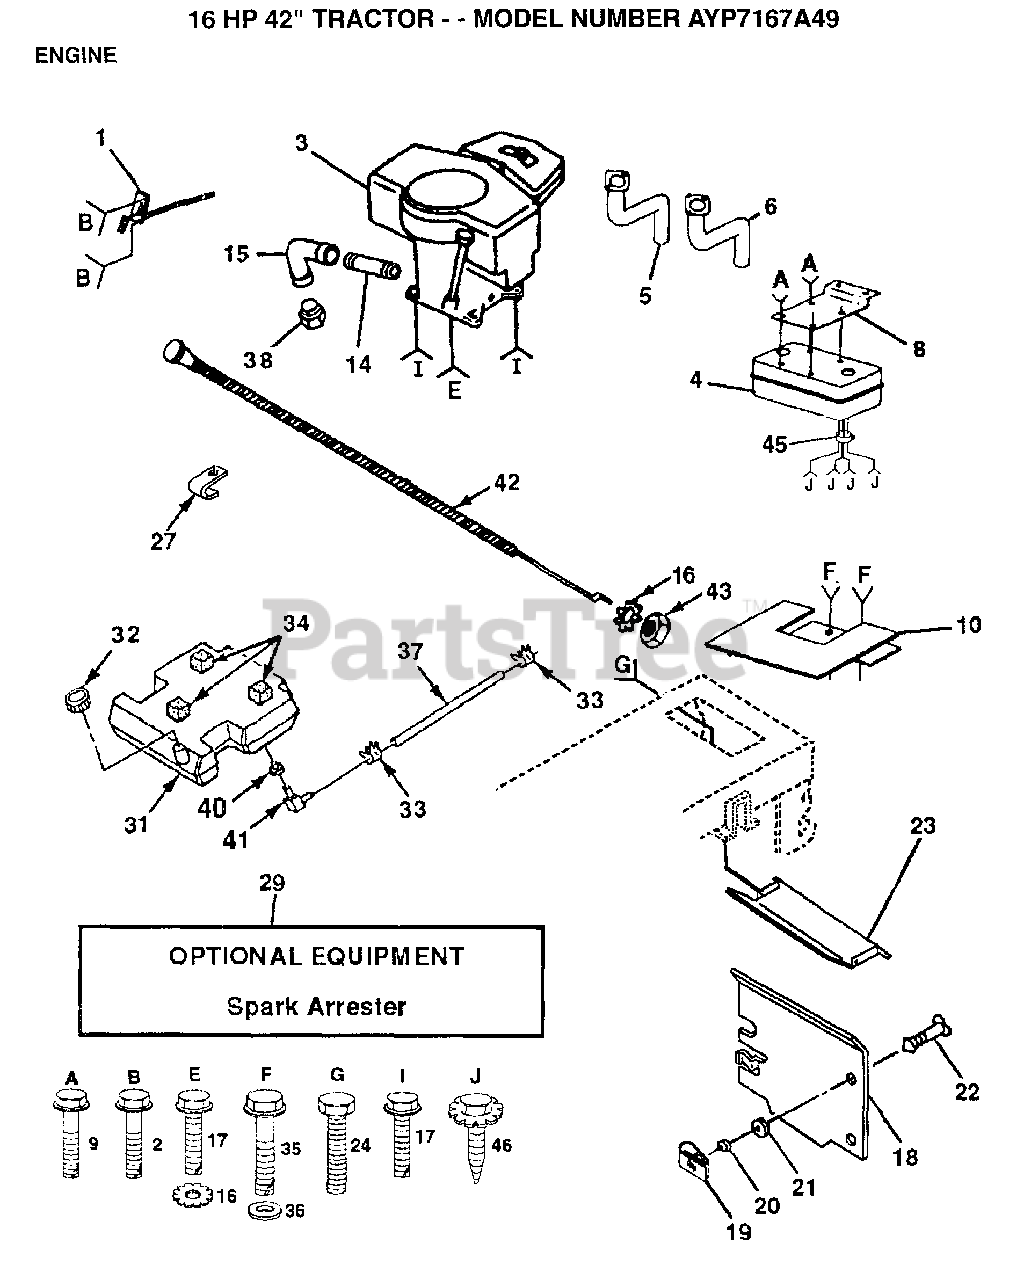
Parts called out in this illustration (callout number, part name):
1	CONTROL THRT 35.5
2	SCREW LT
5	TUBE ASSY EXH LH
6	TUBE ASSY EXH RH
8	BRACKET MUFFLER
9	SCREW ST
10	SHIELD HEAT LT
14	PIPE NIPPLE LT
15	ELBOW
16	LOCKWASHER
17	SCREW
18	SHIELD HEAT
19	RECEPTACLE LT
20	RETAINER LT
21	WASHER
22	STUD.1/4.TURN
23	HEAT SHIELD
24	SCREW
27	"CLIP,INSULATOR"
32	CAP ASM FUEL
33	HOSE CLAMP
34	PAD-SPACER LT
35	SCREW
36	WASHER
37	FUEL LINE T
39	PAD IDLER TI
40	BUSHING OUTLET T
45	DEFLECTOR.222573
